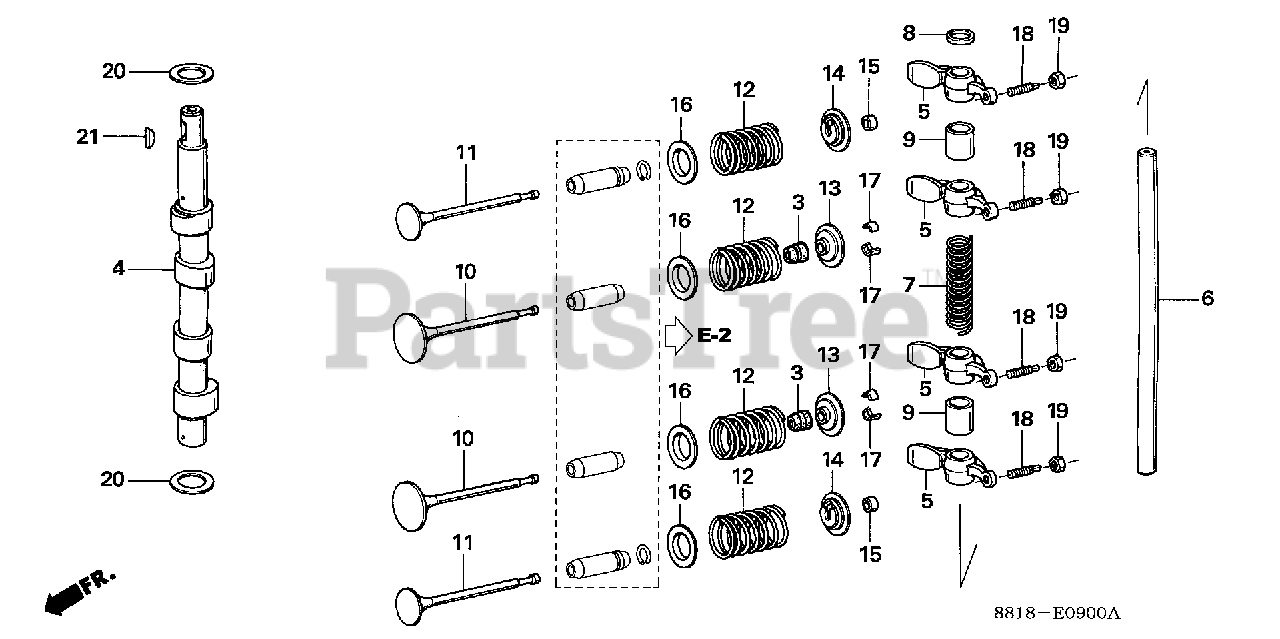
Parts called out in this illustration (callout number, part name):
3	SEAL, VALVE STEM
5	ARM, VALVE ROCKER
6	SHAFT, VALVE ROCKER ARM
7	SPRING, VALVE ROCKER ARM
8	COLLAR A, VALVE ROCKER ARM
9	COLLAR B, VALVE ROCKER ARM
10	VALVE, IN.
11	VALVE, EX.
12	SPRING, VALVE
13	RETAINER, VALVE SPRING
14	RETAINER, VALVE SPRING
15	ROTATOR, VALVE
16	SEAT, VALVE SPRING
17	COTTER, VALVE
18	SCREW, TAPPET ADJUSTING
19	NUT, TAPPET ADJUSTING
20	WASHER, THRUST (16MM)
21	KEY, WOODRUFF (16X12) (SOURCE: VINTAGE PARTS INC.)
